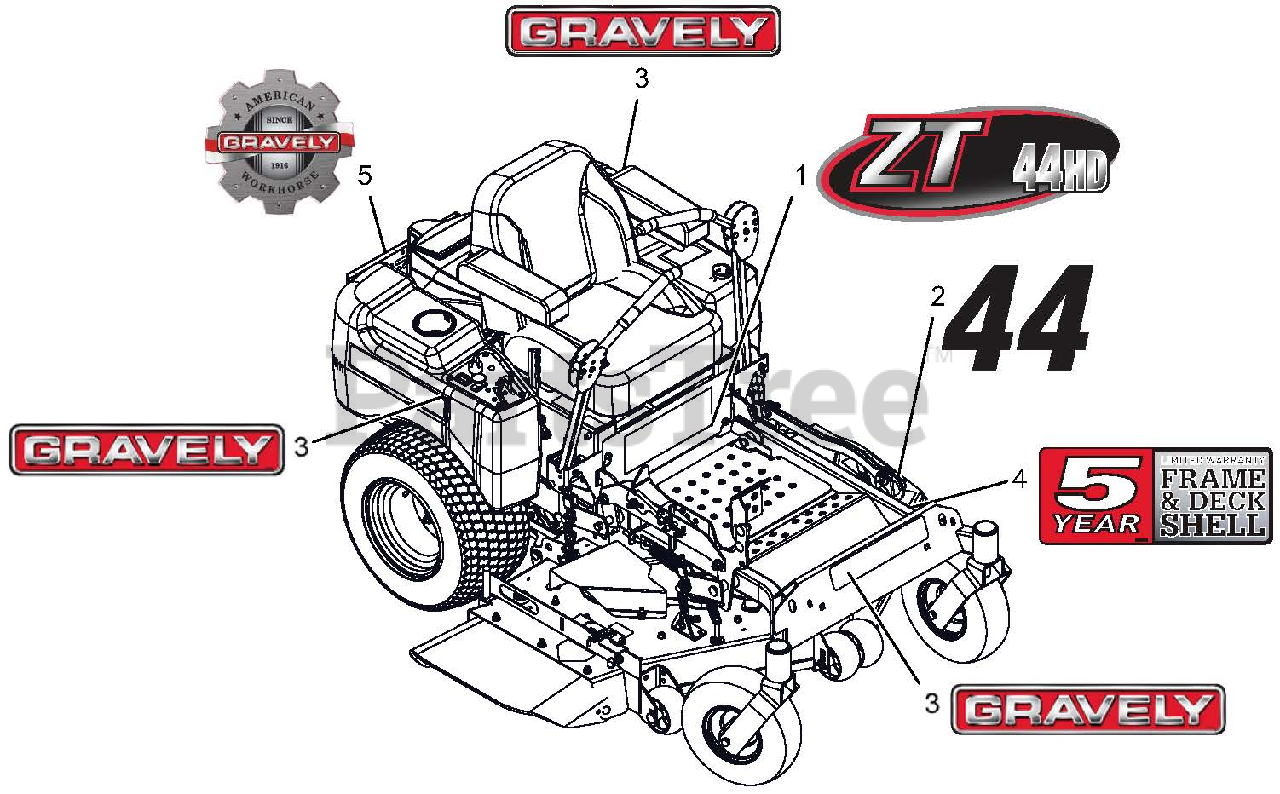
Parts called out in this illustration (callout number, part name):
1	DECAL, 44HD
2	DECAL, 44’’
3	DECAL, FUEL TANK-GRAVELY
4	DECAL, DECK WARRANTY-FAB GRAVELY
5	DECAL, GRAVELY HERITAGE-SMALL
